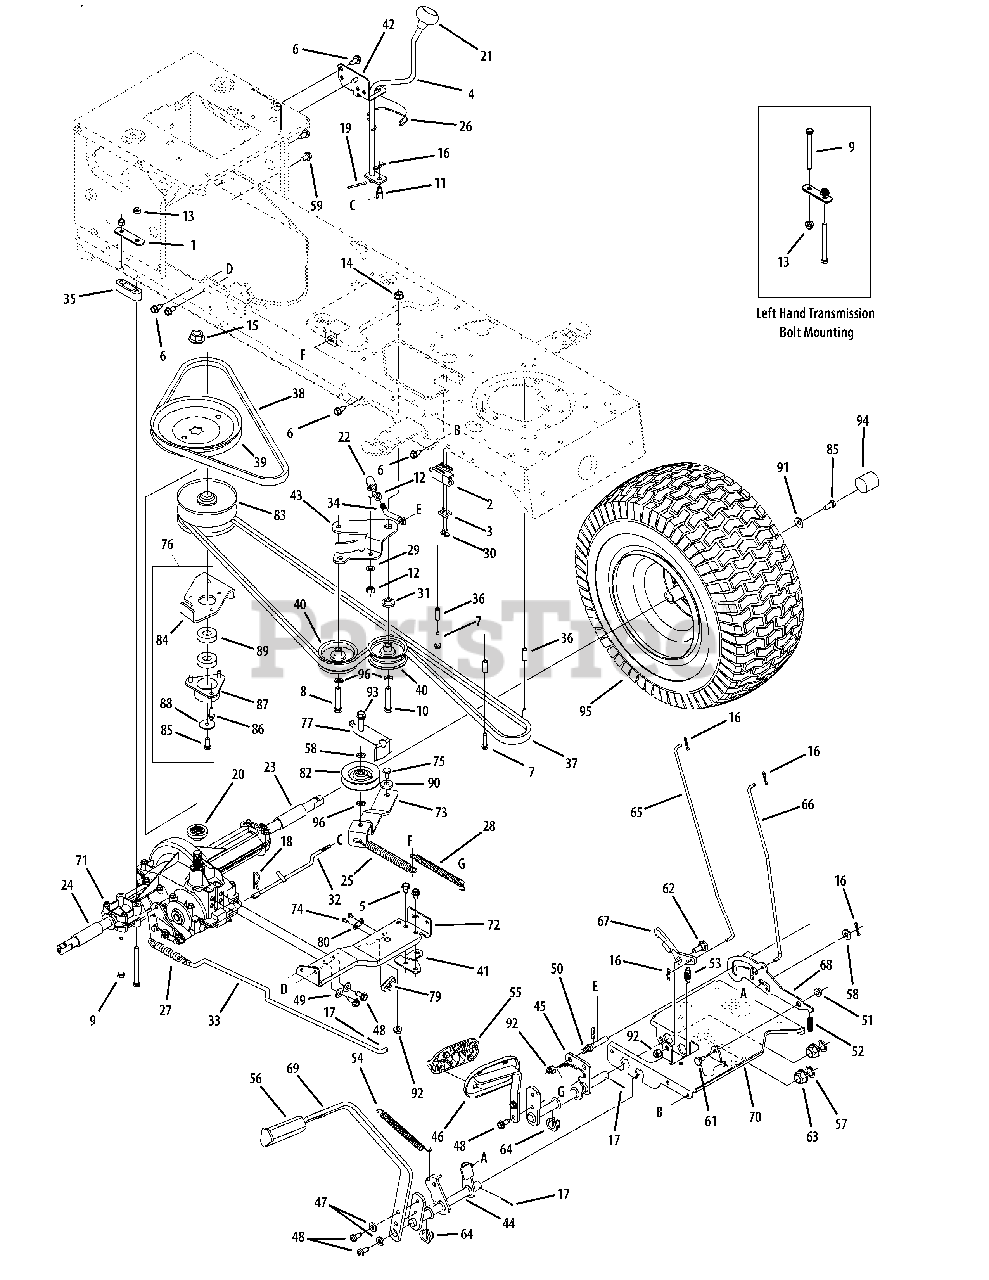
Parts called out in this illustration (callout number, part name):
1	Mounting Bracket, Transaxle
2	Switch, Interlock
3	Plate, Switch
4	Lever Assembly, Shift
5	Screw, 5/16-18, 0.500
6	Screw, 5/16-12, 0.750
7	Screw, 1/4-20, 1.250
8	Screw, Sems, 3/8-16, 1.500
9	Screw, 5/16-18, 3.50, Gr5
10	Screw, 3/8-16, 2.00, Gr5
11	Adjustment Ferrule 1/4-20 x 1.
12	Nut, Hex, 3/8-24, Gr5
13	Nut, Flange Lock, 5/16-18, GrF
14	Nut, Flange Lock, 3/8-16, GrF
15	Nut, Flange, 9/16-18, Gr2
16	Pin, Cotter,.072 Dia. x 1.13
17	Pin, Cotter, 3/32, 1.0
18	Cotter .Pin, Internal,.125 Dia.
19	Pin, Cotter, 1/8 x 1.25
20	Pulley Hub, 5/8 Spline
21	Knob, Shift
22	Ball Joint
23	Sleeve,.758 x.821 x 3.3125
24	Sleeve,.758 x.821 x 2.4375
25	Spring, Extension,.62 Dia x 6.12
26	Spring Clip, Shifter
27	Spring, Extension,.59 OD x 4.00
28	Spring, Extension,.50 Dia x 6.37
29	Washer, Lock, 3/8
30	Screw, #10-16,.50
31	Spacer, Shoulder, 1.00 x.38 x.38
32	Rod, Shift
33	Rod, Brake
34	Idler Rod, Adjustable, 3/8
35	Spacer,.68
36	Spacer,.260 x.372 x 1.030
37	Belt, V-Type
38	Belt, V-Type
39	Pulley, V-Type, 7.25 Dia.
40	Idler Pulley, Flat 2.75 OD
41	Bracket, Shift
42	Bracket, Shift, F-N-R
43	Idler Bracket, Center Double
44	Control Assembly, Brake
45	Control Assembly, Speed
46	Pedal Assembly
47	Lock Washer, 5/16
48	Screw,5/16-18, 0.750
49	Washer, Flat, .330 x .630 x .0635
50	Pin, 3/8-16 x 2.68
51	Nut, Flange Lock, 5/16-18, Gr5
52	Spring, Compression.,.405 x 1.17
53	Spring, Extension,.50 OD x 1.41
54	Spring, Extension,.50 OD x 6.37
56	Pad, Brake
57	Washer, Flat,.64 x 1.24 x.06, Ht
58	Washer, Flat,.385 x.870 x.092
59	Hex Screw
61	Screw, Shoulder.437 Dia x.162
62	Screw, Shoulder,.50 x.27 Lg,
63	Bearing, Hex Flange
64	Split Bearing, Hex Flange
65	Rod, Brake Lock
66	Rod, Cruise Control
67	Latch, Cruise Control
68	Bracket, Lockout
69	Pedal, Brake
70	Bracket, Steering Support
71	Transmission, Single Speed
72	Bracket Assembly, Torque
73	Bracket, Idler
74	Screw, #8-18 x.50
75	Hex Screw, 3/8-16 x 1.25
76	Variable Speed Pulley Assembly
77	Belt Guard
79	Switch Spring, Short
80	Plate, Insulator
82	Idler Pulley, V-Type, 5L x 3.06
83	Pulley, Variable Speed
84	Bracket, Pulley
85	Screw, 5/16-24,.750
86	Screw, 1/4-20, 1.500
87	Cup, Bearing
88	Washer, Flat
89	Ball Bearing
90	Shoulder Spacer, .8840 x .190
91	Washer, Bell,.340 x.872 x.060
92	Nut, Flange Lock, 3/8-16, GrF
93	Screw, Sems, 3/8-16, 2.500
94	Hub Cap
95	Wheel Assy Comp, 20 x 8 x 8
96	Flat Washer, .407 x .812 x .135
